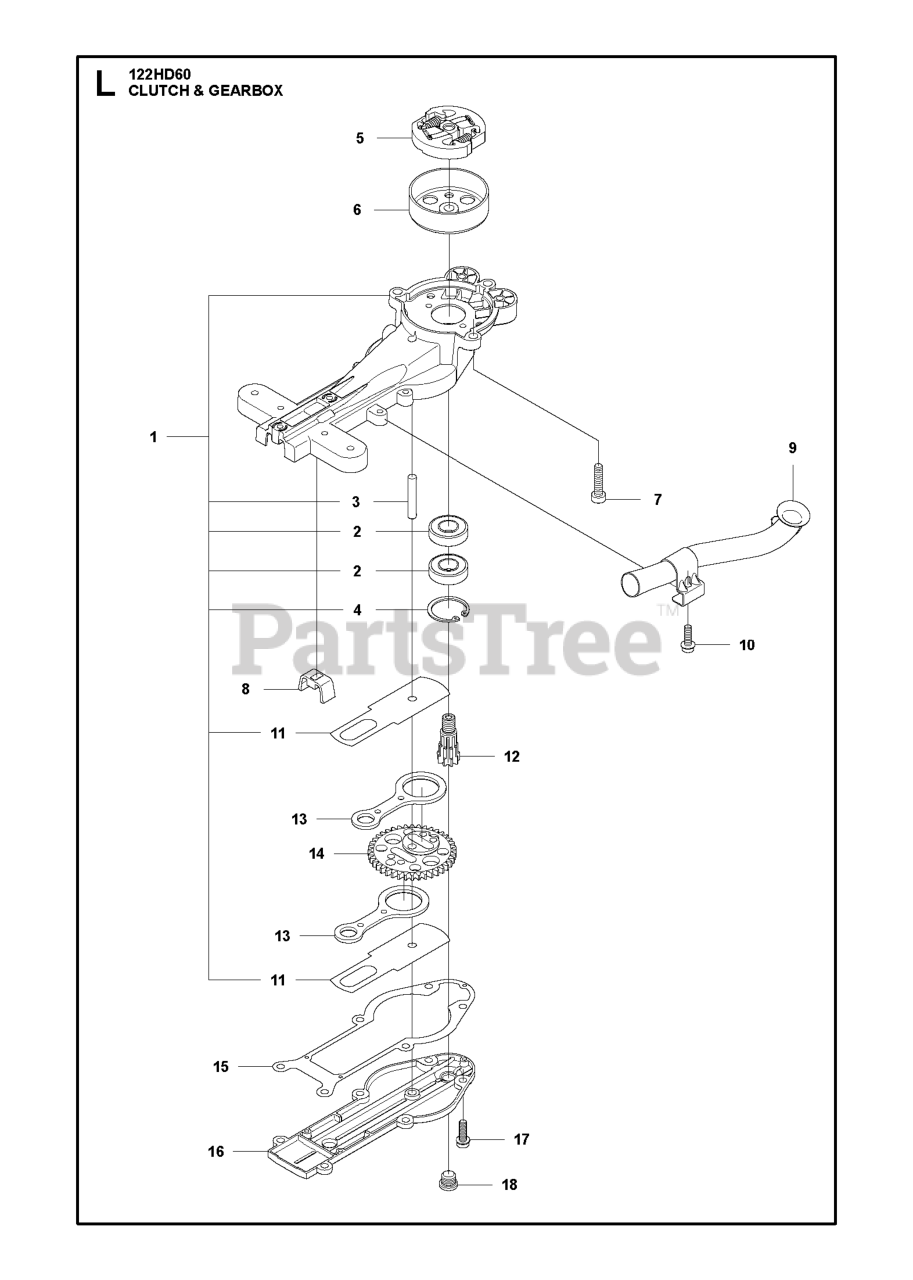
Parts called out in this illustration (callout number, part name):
2	BALL BEARING
5	CLUTCH ASSY
6	CLUTCH DRUM ASSY
9	EXHAUST PIPE ASSY.
11	WEAR PLATE
12	GEAR WHEEL SHAFT
13	CONNECTING ROD
14	GEAR WHEEL
